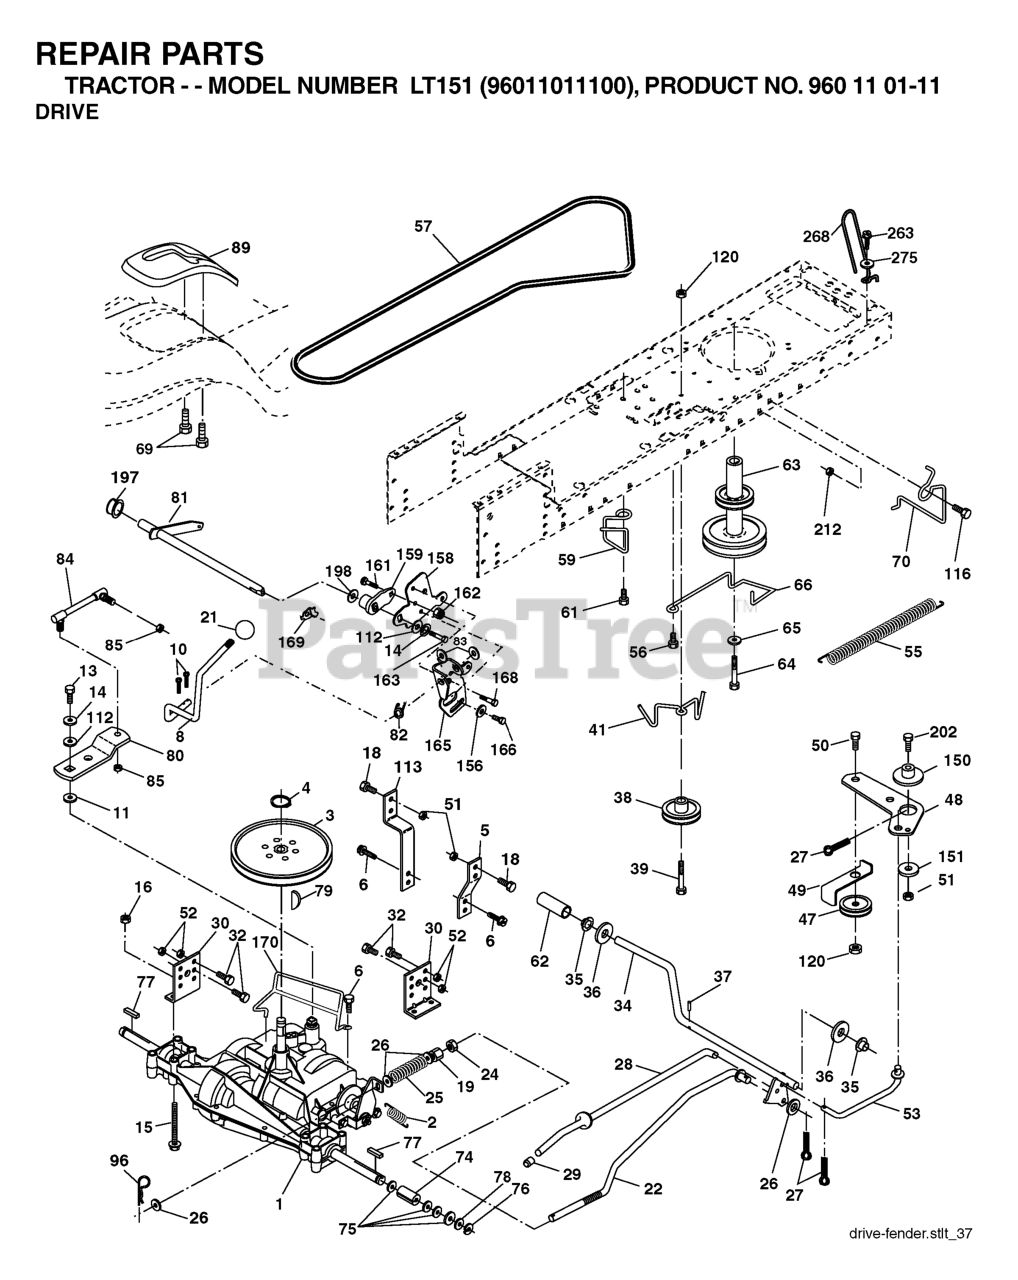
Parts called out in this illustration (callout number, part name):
2	SPRING,BRAKE RETURN
3	PULLEY TRANS
4	RETAINING RING LT
5	STRAP TORQUE
6	SCREW 5/16"
8	ROD.SHIFT.FENDER.ADJ.STLT
10	PIN COTTER
11	WASH-SHFT PLT LT
13	BOLT 1/4-28X3/4
14	LOCKWASHER
15	BOLT HEX 5/16-18 GR 5
16	NUT.71038.31-18.HEX.NYLOCK
19	NUT
21	KNOB.DUCKHEAD.1/2
24	NUT
25	SPRING ROD LT
26	WASHER
27	COTTER PIN
28	ROD, PARKING BRAKE
29	PLUNGER CAP
30	BRKT, MOUNT TRNSAXLE
32	BOLT
34	SHAFT, FOOT PEDAL
35	BEARING.NYLON
37	DRIVE PIN
38	PULLEY IDLER COMPOSITE
41	KEEPER, BELT IDLER
47	IDLER PULLEY
48	BELLCRANK, CLUTCH
49	RETAIN BELT
50	BOLT.3/8-16X1.50
52	LOCKNUT
53	LINK.CLUTCH.7.66.2005
55	SPRING, RETURN LT
56	SCREW.3/8-16
57	BELT, V GROUND DRIVE 95 25
59	KEEPER, BELT CENTER
61	SCREW 3/8-16X.875
62	PEDAL COVER T
63	ENGINE PULLEY
64	BOLT HEX 7/16-20X4-1/4"
65	LOCKWASHER
66	KEEPER BELT ENGINE
69	SCREW.HI-LO.CONSOLE
70	KEEPER BELT ENG
74	SPACER AXLE
77	SQUARE KEY
79	KEY STD (1373) DANA
81	SHAFT ASM CROSS TAPERED
82	SHIFT SPRING
83	WASHER
84	LINK.TRNSAXLE
85	NUT LOCK CENTER 1/4 -28 FNTHD
89	CONSOLE.SHIFT.STLT.6SP
96	RETAINER M
113	STRAP TORQUE LH LT
116	BOLT D
120	NUT LOCK FLG 3/8-16 UNC
150	SPACER, RETAINER
151	WASHER 12/32X2X10GA
156	WASHER.SRRTD.5/16
158	BRACKET
159	RB HUB.SHIFT
161	BOLT
162	NUT.CROWNLOCK.1/4
165	RP BRACKET
166	CAPSCREW.HXHD.FLG.5/16-18X.625
168	BOLT.SHOULDER.5/16-18X
169	PLATE.FASTENING.CROSS.SHAFT
170	KEEPER BELT T/A
197	NYLINER SNAP 5/8" ID
198	WASHER.NYL.7/8IDX.105"HYD CR
212	NUT
263	SCREW, 3/8-16X3/4
268	GUARD MUFFLER
275	WASHER
